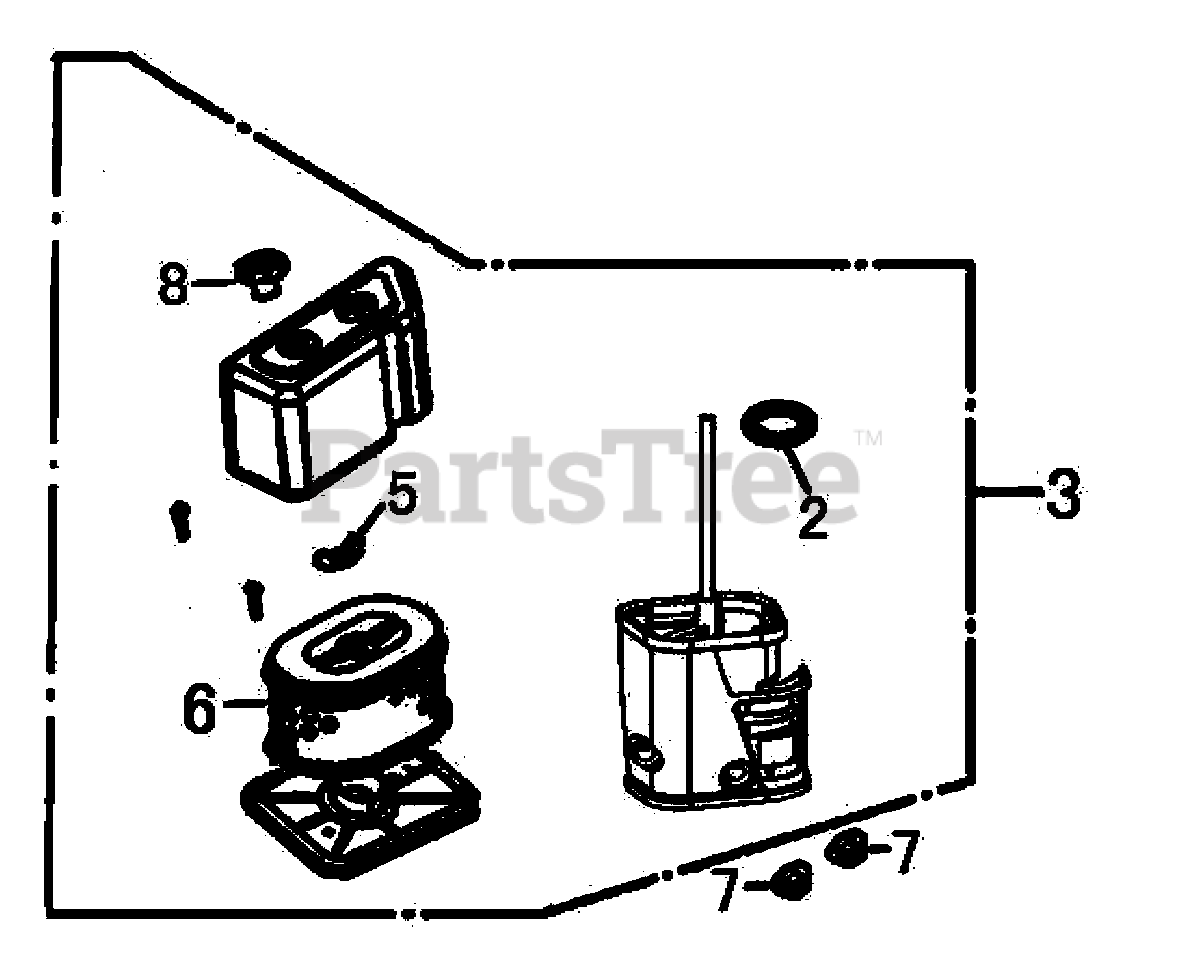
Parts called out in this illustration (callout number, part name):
2	GASKET, ELBOW
3	CLEANER ASSY., AIR
5	NUT, TOOL BOX SETTING
6	ELEMENT ASSY., AIR CLEANER
7	NUT, FLANGE
8	BOLT, HANDLE KNOB
